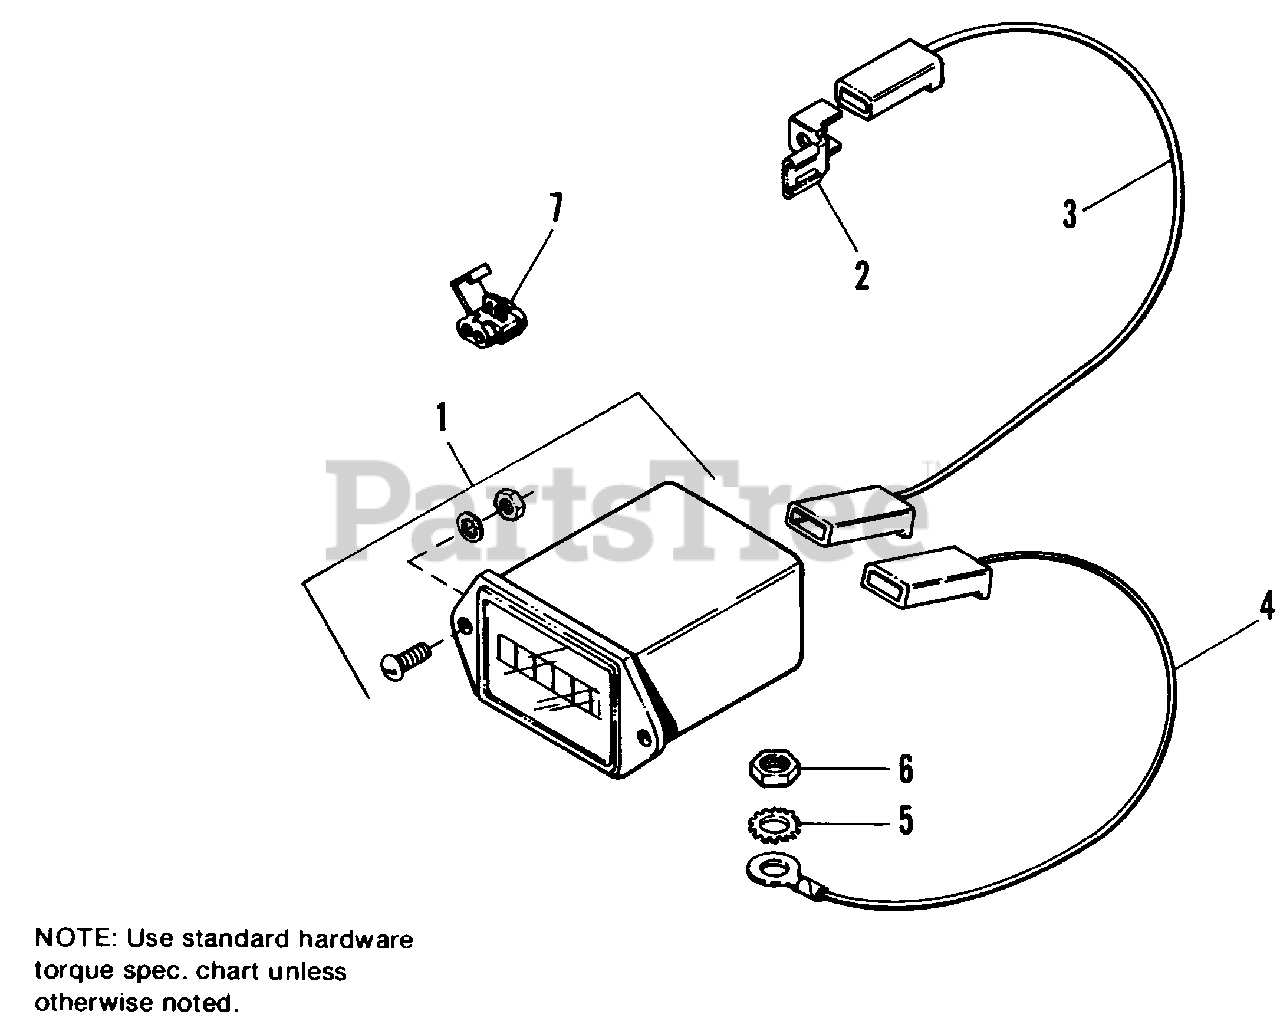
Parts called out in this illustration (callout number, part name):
1	HOURMETER
2	ADAPTOR, 2-Way
3	WIRE ASSY.
4	CONNECTOR ASSY., 15-1/2
5	LOCKWASHER, Ext. Tooth, 1/4
6	NUT, Hex, Full 1/4-20
7	CONNECTOR, Wire, Self-Stripping
